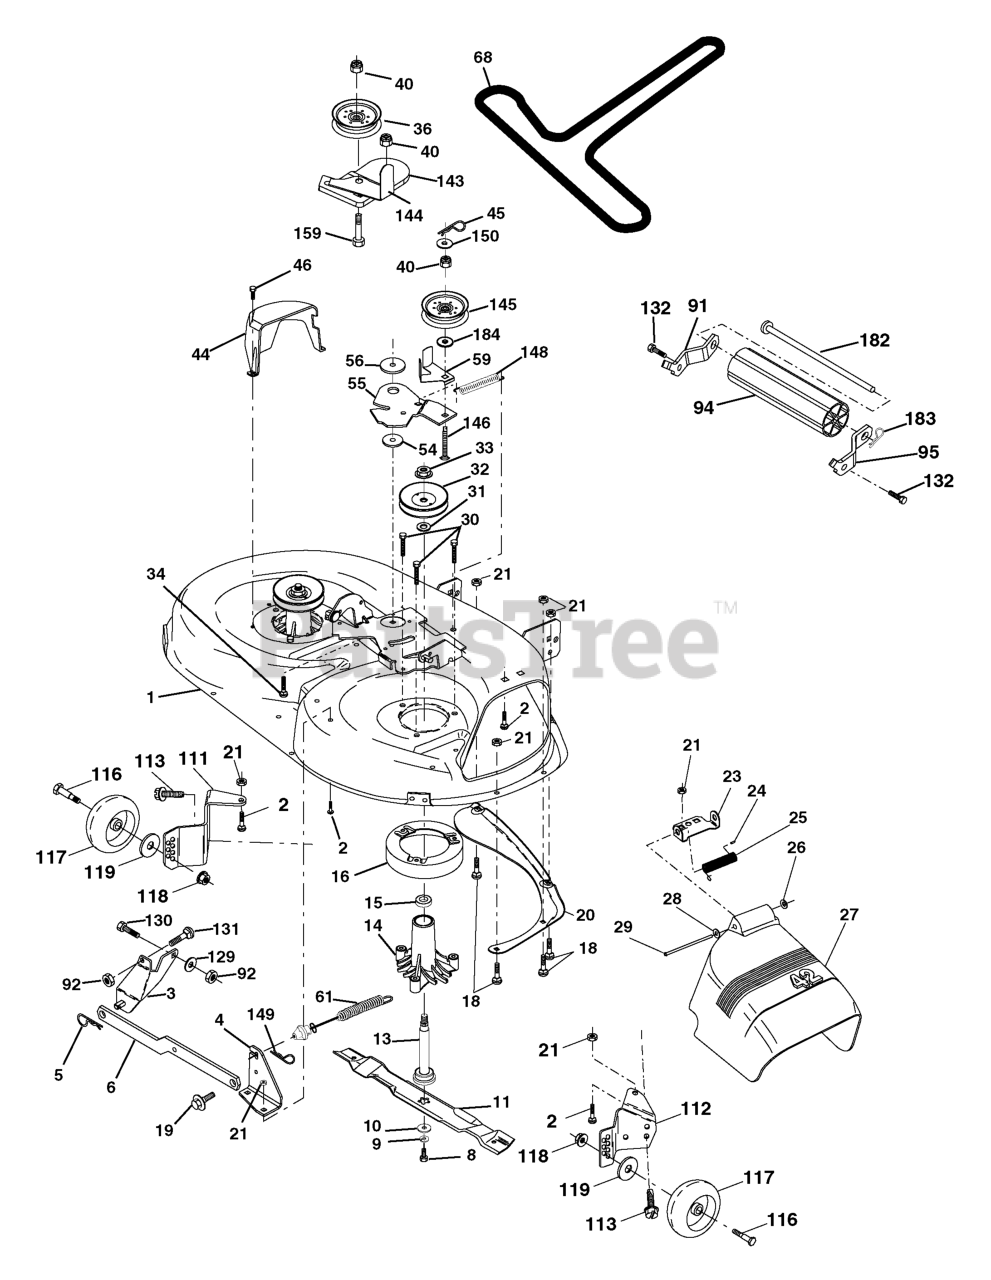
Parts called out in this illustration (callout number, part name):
1	DECK SVC 42"
2	RP BOLT 5/16-18 X3/4 ZN/YEL GR
3	BRKT ASM SWAY BAR
4	BRACKET SWAY BAR 42" DECK
5	RETAINER-SPRNG RB
6	BAR SWAY DECK
8	BLADE BOLT
9	LOCKWASHER
10	WASHER.BLADE
11	42" HI-LIFT BLADE
11	BLADE.42".MULCH
11	BLADE.42"MULCH.PREMIUM
13	SHAFT ASM VENT
14	HOUSING.MANDREL.VENTED (MACHD)
16	STRIPPER.MANDREL.ROUND.BLACK
18	BOLT
19	BOLT SHD 5/16-18
20	BAFFLE.VORTEX
21	LOCKNUT
23	BRKT, DEFL. MOWER
24	CAP-SLEEVE LT
25	SPRING TORSION
26	NUT PUSH M
27	SHIELD DEFLECTOR
28	Washer 11/32 x 5/8 x 16 Ga.
29	ROD.HINGE
30	SCREW, WASHER HEAD
31	WASHER.SPACER.MANDREL
32	PULLEY/MANDREL
33	NUT, FLG TOPLOCK 9/16"
34	BOLT.3/8-16X1.50
36	FLAT IDLER PULLEY
40	NUT LOCK FLG 3/8-16 UNC
44	GUARD MANDREL LH BLACK
45	RETAINER M
46	SCREW.1/4-20X5/8
55	ARM IDLER 42" MOWER LT/YT
56	SPACER.RETAINER.MOWER
59	GUARD, BELT
61	SPRING EXT ELEC CLUTCH
68	V-BELT PRIMARY 42"
91	BRACKET ASM NOSEROLLER LH
92	NUT
94	NOSE ROLLER
95	BRACKET ASM NOSEROLLER RH
111	BRACKET, WHEEL
112	BRACKET, WHEEL
113	BOLT.5/16HEX.WHS.HD
116	BOLT M
117	WHEEL.GAGE.HALF.SPOKED
118	LOCKNUT
119	WASHER.5/16.FLAT.STE.STD.
129	WASHER
130	BOLT
131	BOLT D
132	SCREW, 3/8-16X3/4
143	BRACKET, ARM IDLER
144	DNO KEEPER.BELT.42".CLUTCH.CBL
145	PULLEY
146	BOLT, CARRIAGE IDLER BLACK
148	IDLER RETURN SPRING
149	SPRING.RETAINER.YELLOW.ZINC
150	WASHER LT
159	BOLT
182	ROD ROLLER NOSE STANDARD
183	SPRING RETAINER
184	WASHER
